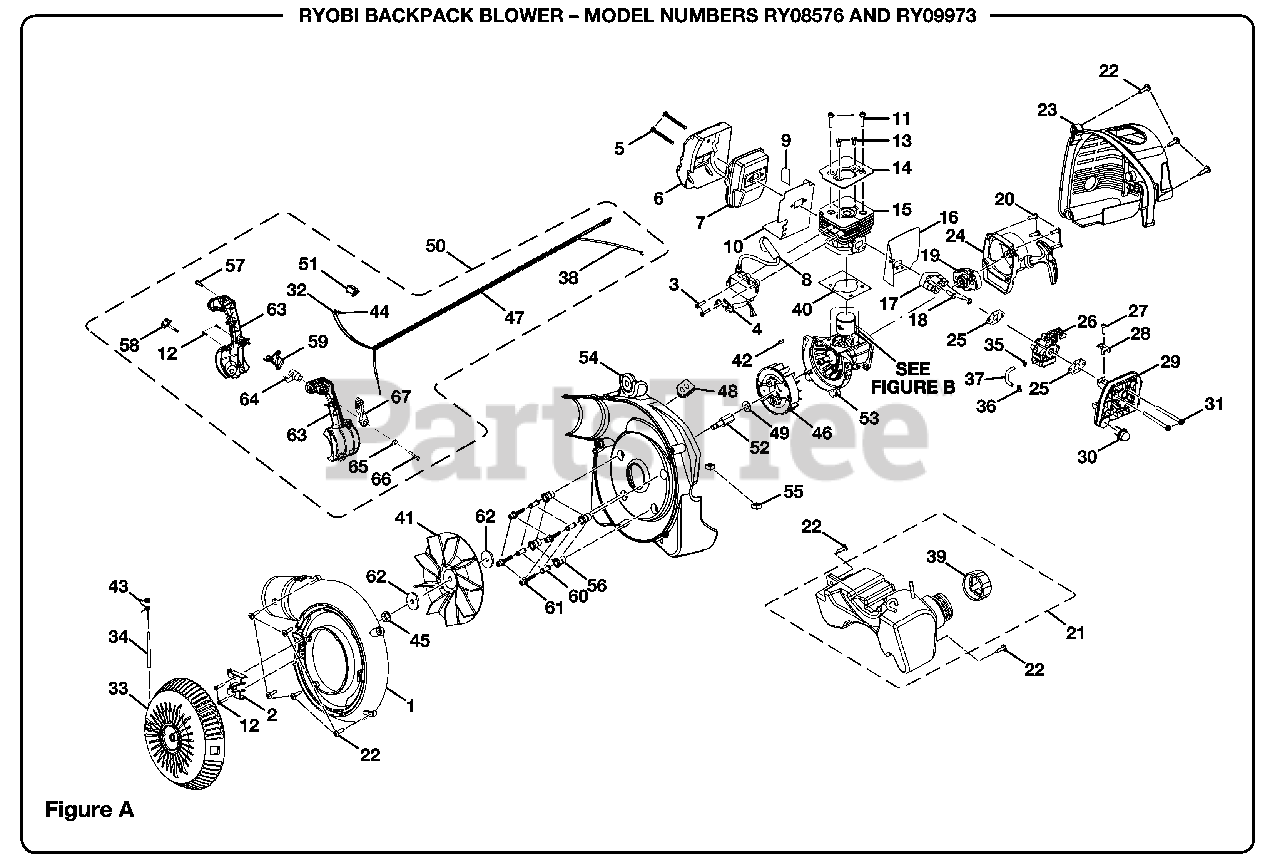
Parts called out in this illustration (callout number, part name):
1	Outer Volute Housing
2	Vacuum Door Hinge
3	Screw (M4 X 22 mm)
4	Lead Assembly
5	Screw (M5 X 50 mm)
6	Heat Shield
7	Muffler Assembly
8	Coil & Boot Assembly
9	Heat Shield
10	Gasket Muffler
11	Screw (M5 X 22 mm)
12	Screw (#8-14 X 16.3 mm)
13	Screw & Washer (M5 X 10 mm)
14	Plate for Cylinder
15	Cylinder
16	Insulator Gasket
17	Insulator
18	Screw & Washer (M5 X 31 mm)
19	Pulley Assembly
20	Screw (M5 X 16 mm)
21	Fuel Tank Assembly
22	Screw (#10-14 X 7/8 in.)
23	Engine Shroud Housing
24	Starter Assembly
25	Carburetor Gasket
26	Carburetor
27	Screw (M4 X 1.75 X16 mm Pan Hd.)
28	Clip-throttle Cable
29	Air Box Base
30	Primer Assembly
31	Screw (M5 X 60 mm)
32	Lead Assembly (Red)
33	Vacuum Door
34	Hinge Pin
35	Clip-hose (Id 4.9)
36	Clip-hose
37	Tubing Rubber
38	Cable Assembly
39	Fuel Cap Assembly
40	Cylinder Gasket
41	24.5 Cc Blower Fan
42	Key Woodruff (S43C)
43	Vacuum Door Hinge Spring
44	Lead Assembly (Black)
45	Retaining Washer Nut
46	Fly-wheel Assembly
47	Corrugated Tube
48	Rubber Grommet
49	Washer (2 mm)
50	Control Assembly
52	Crank Shaft Extension
53	Crankcase Assembly
54	Housing Inner Volute
55	Square Nut
56	Vibration Isolator
57	Screw (#10-14 X 25 mm)
60	Bushing Sleeve
61	Screw (M5 X 8 mm Cap Hd.)
62	Washer-fan Spacer
63	Handle Assembly
64	Trigger Lock
66	Screw (#8-14 X 50 mm)
67	Crulse Lever
